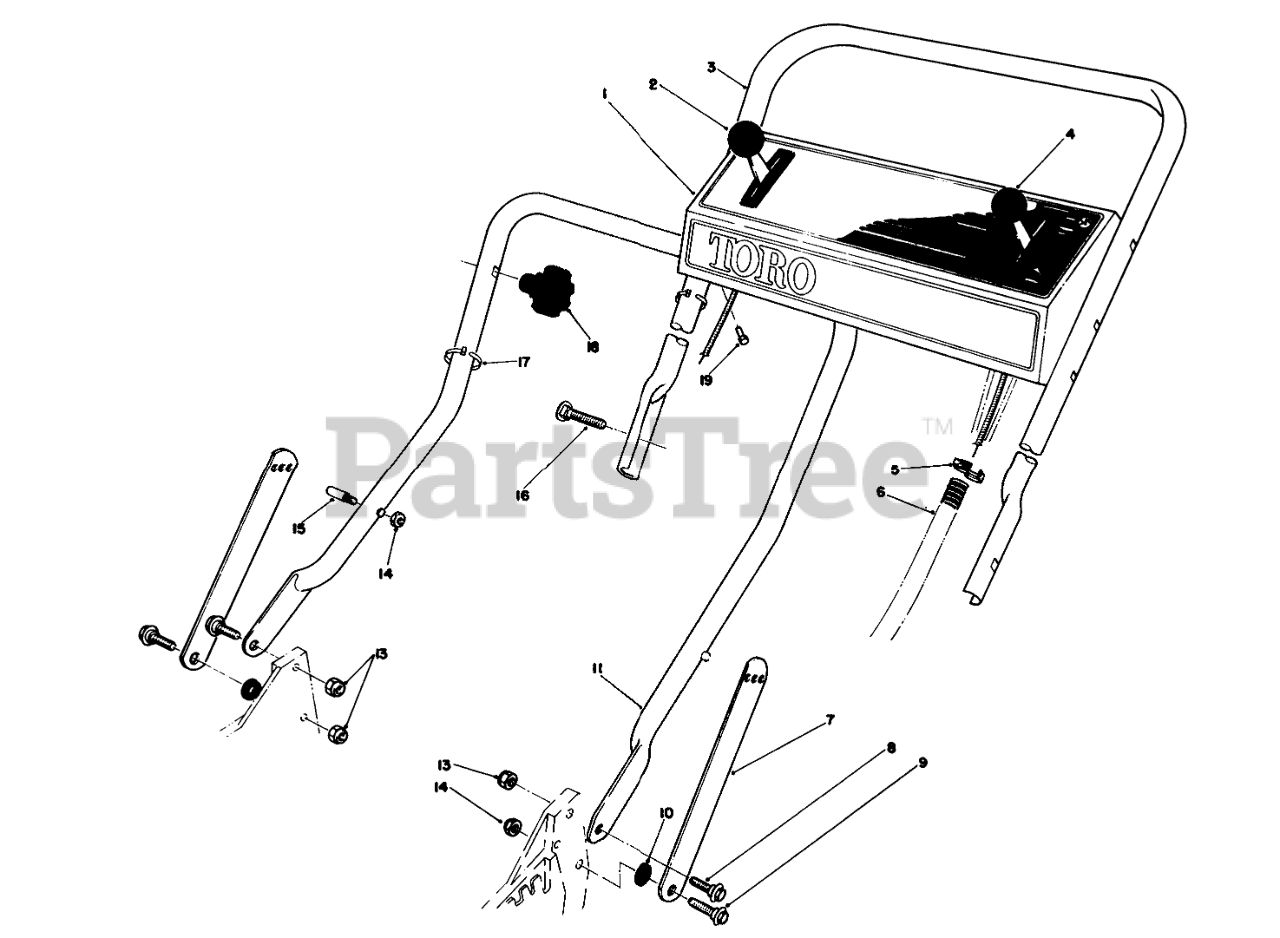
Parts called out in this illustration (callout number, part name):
1	4320 Panel-Control
2	GROUND SPEED CONTROL
3	Handle-Upper
4	THROTTLE CONTROL
5	FITTING-RING
6	CONTROL CABLE COVER
7	Handle Latch
8	SCREW-SHOULDER
9	SCREW-SHOULDER
10	SPACER
11	LOWER HANDLE ASM
13	NUT-LOCK, NI
14	Locknut
15	HANDLE PIN
16	5/16-18 X 2 HNDLE SCREW
17	TIE-CABLE
19	SCREW-HWHTF
